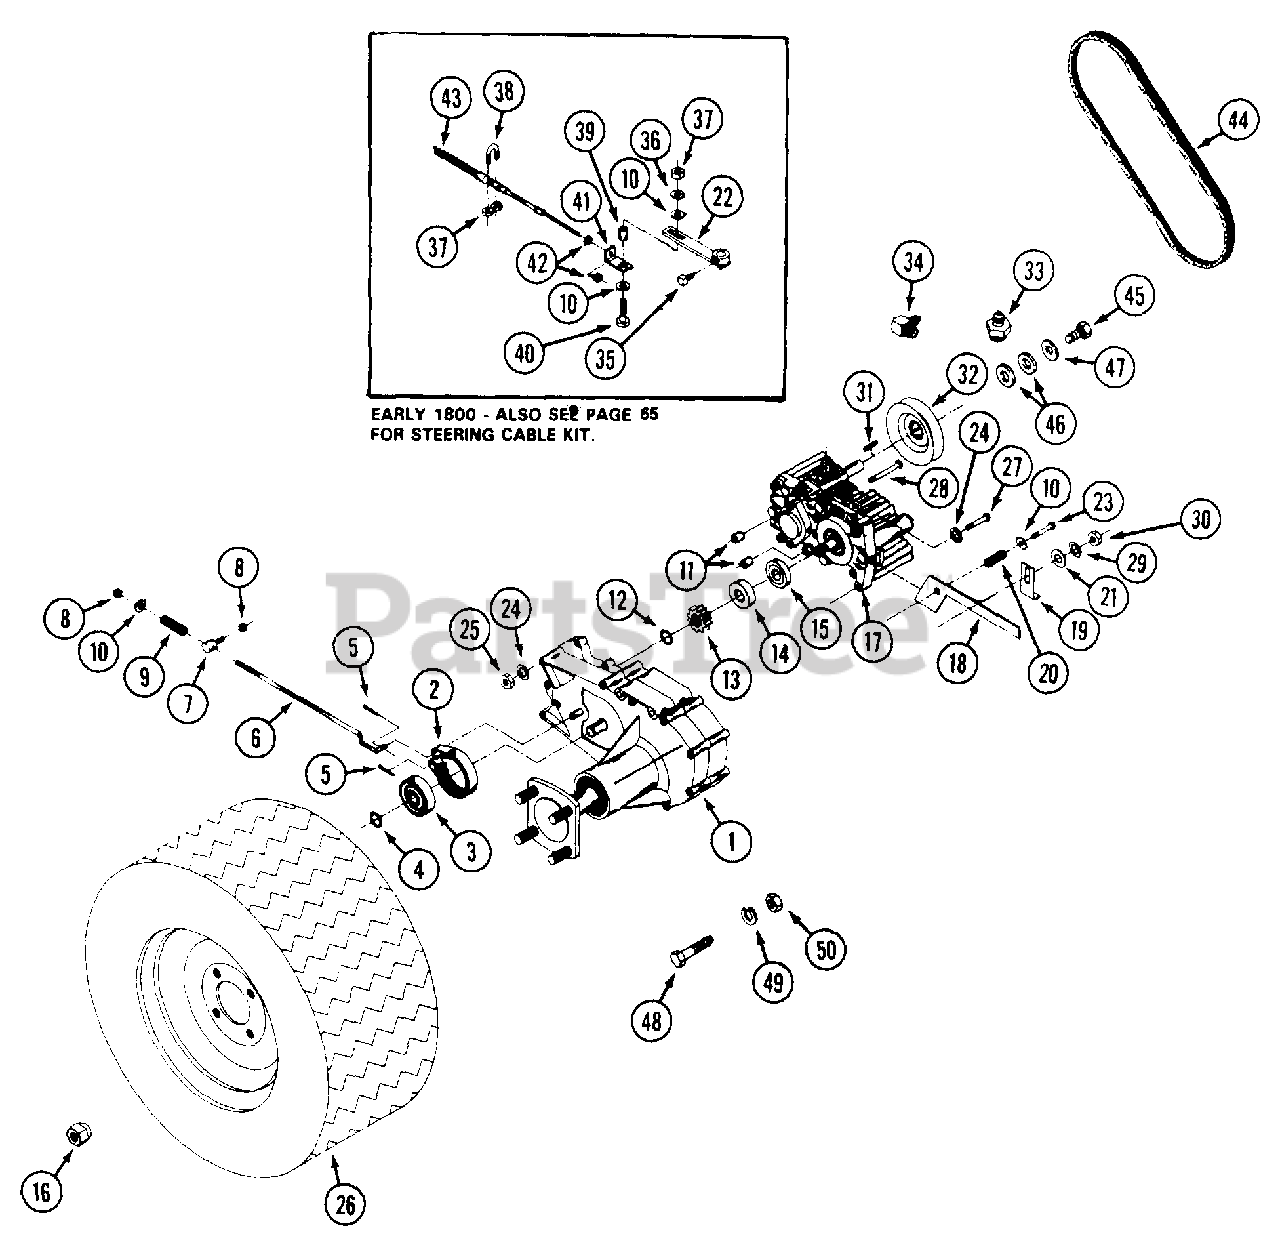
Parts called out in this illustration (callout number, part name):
1	TRANSMISSION - ZT
5	PIN - cotter 1/8" x 1"
7	COLLAR - brake rod
8	NUT - lock 1/4"-20
10	WASHER - 1/4"
12	RING - snap
14	BEARING
16	NUT - lug 1/2"-20
17	PUMP - hydro R.H.
18	LEVER - transmission dump
19	BRACKET - dump lever stop
20	SPRING - compression
21	WASHER - 3/8"
22	ARM - transmission
23	BOLT - dump valve
24	LOCKWASHER - 5/16"
25	NUT - 5/16"-18
26	WHEEL ASSEMBLY
27	BOLT - 5/16"-18 x 1-3/4"
28	BOLT - 5/16"-18 x 7-1/2"
29	LOCKWASHER - 3/8"
30	NUT - 3/8"-16
31	KEY - 5 x 5 x 25mm
32	PULLEY - 4" OD x 15 mm ID
34	ADAPTER - 90°
35	SCREW - set 5/16"-18 x 1/2" square head
36	LOCKWASHER - 1/4"
37	NUT - 1/4"-20
38	CLAMP - cable
39	BUSHING - cable
40	BOLT - 1/4"-20 x 1"
41	BRACKET - cable end
42	NUT - lock #10-32
44	BELT - pump drive
45	BOLT - M6-1.0 x 12m flange
46	WASHER - .625" x 1"
47	WASHER - .312" x .875"
48	BOLT - 3/8"-16 x 3-1/2" mounting
48	BOLT - 3/8"-16 x 4" mounting
49	LOCKWASHER - 3/8"
50	NUT - 3/8"-16
